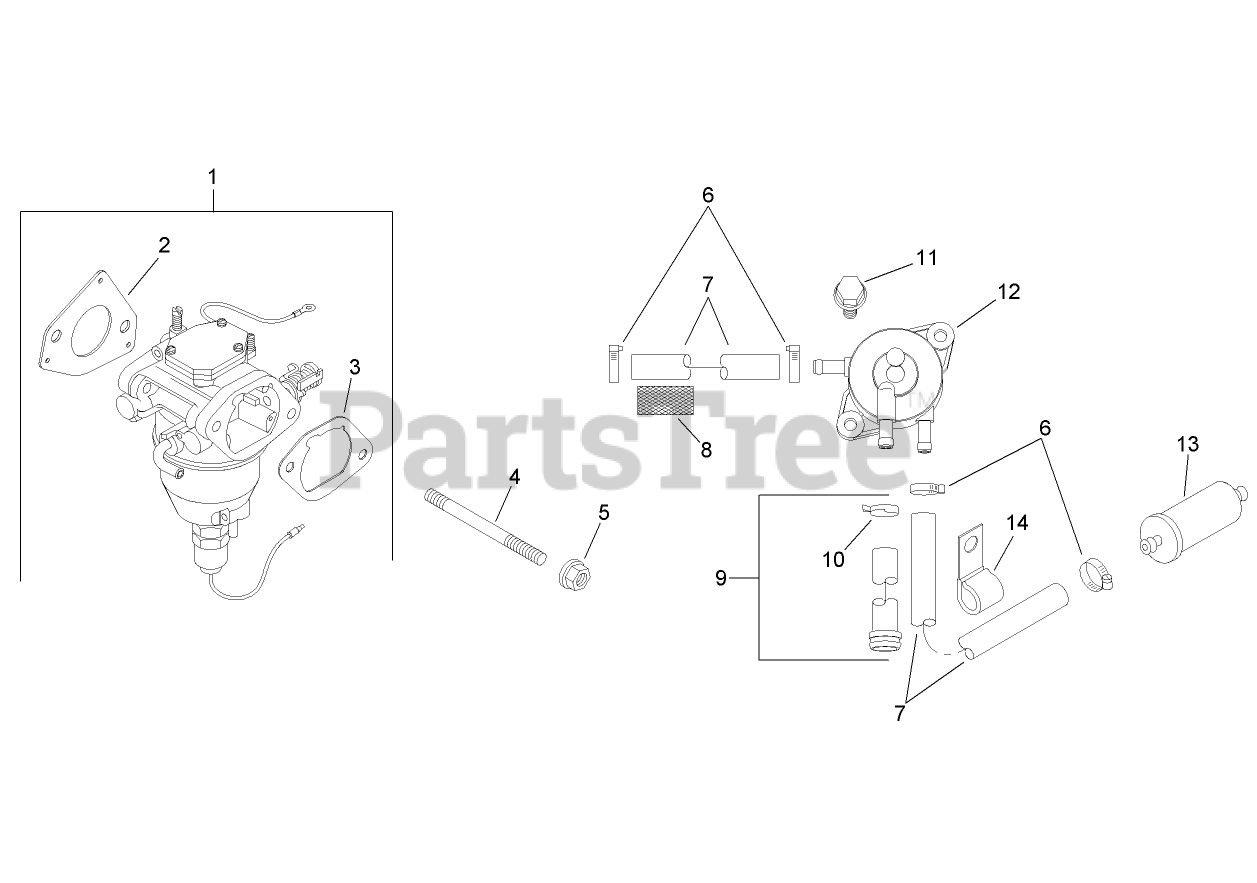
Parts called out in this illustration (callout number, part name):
1	CARBURETOR KIT W/GASKETS (INCLUDES 2-3)
2	GASKET-CARBURETOR
3	GASKET-BASE, AIR CLEANER
4	STUD (M6X1.0X106)
5	NUT-FLANGE (M6X1.0)
6	CLAMP-HOSE, SPRING (1/2)
7	LINE-FUEL (24-CUT TO LENGTH)
8	SLEEVE-ABRASION, ANTI
9	HOSE-FUEL PUMP W/CLAMP (INCLUDES 10)
10	CLAMP-HOSE
11	SCREW-TAP (M6X1.7X18)
12	PUMP-FUEL
14	CLIP-CABLE
